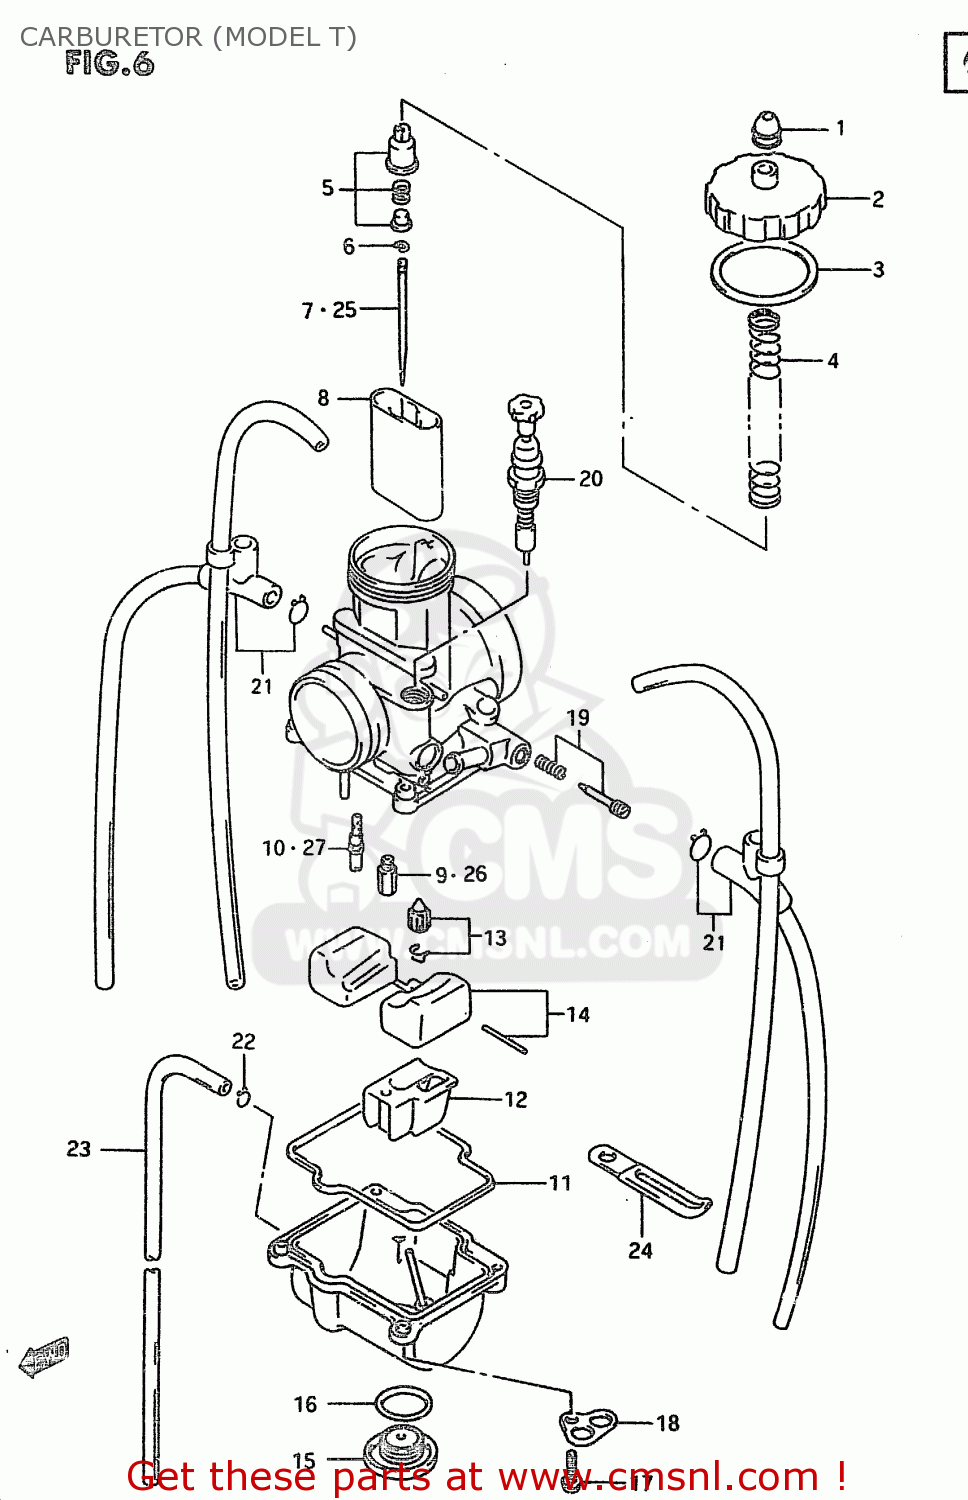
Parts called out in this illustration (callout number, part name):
1	CAP,CARBURETOR
2	CAP,TOP
3	GASKET,TOP CAP
4	SPRING
5	HOLDER SET,CABLE
6	CLIP,NEEDLE
7	NEEDLE(R1467NS)
8	VALVE,PISTON(CA:5.0)
9	JET,MAIN(172)
10	JET,PILOT(58)
11	GASKET,FLOAT CHAMBER
12	HOLDER
13	VALVE SET,FLOAT
14	FLOAT SET
15	BOLT,DRAIN
16	O RING
17	SCREW
18	PLATE
19	SCREW SET,AIR
20	PLUNGER ASSY
21	HOSE SET
22	CLIP
23	HOSE(3.5X6.5X600)
24	CLAMP(L:45)
25	NEEDLE(R1467MS)
26	JET,MAIN(160)
27	JET,SLOW(35)
